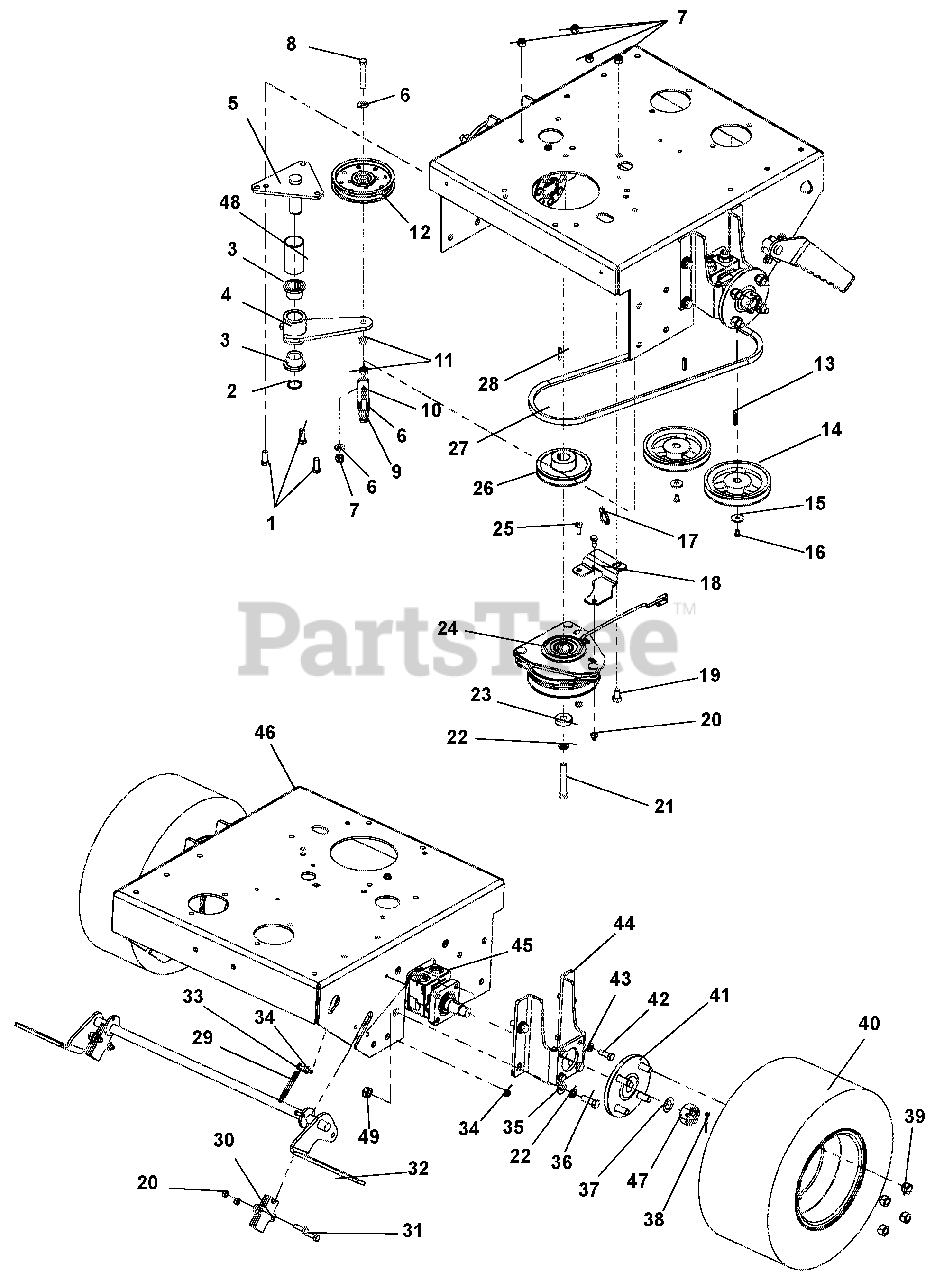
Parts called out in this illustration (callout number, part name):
1	BOLT-HEX .38-16 1.00 GR5
2	SNAP RING, 1.00 X .042 EXT
3	BRG, FLG 1.00 X 1.25 X 1.00
4	WLDT, IDLER ARM
5	WLDT, IDLER PIVOT MOUNT
6	WASHER, .406 X .813 X .065 FLAT Y
7	NUT-LOCKING-NYLON .38-16
8	BOLT, HEX .38-16X2.50 GRADE 5
9	BLT-HEX .38-16X3.00 HEX 8 YWZC
10	SPRING, EXT .900X.135X4.50 Y
11	NUT-SPIN LOCK-FLANGE .375-16
12	PULLEY, FLAT 4.50 X .375 W/BRG
13	KEY, M5 X M5 X M30 RD
14	ASSY, PUMP PULLEY W/SET SCREW
15	WASHER, .250 WIDE HEAVY FLAT Y
16	BOLT, M6 X 1.00 X 10 HEX 8.8 Y
17	CABLE TIE, .15 X 8.50
18	PLATE, CLUTCH DOG
19	BOLT, 7/16-14 X .750 HEX 5 Y
20	NUT-LOCKING-NYLON .312-18
21	BOLT, HEX .44-20 X 3.00 G5
22	WASHER-LOCKING .44X.109 REGULAR
23	SPACER, .468 X 1.38 X .375 Y
24	CLUTCH ASSY, OGURA
25	BOLT, HEX .31-18 X .75 GR5
26	PULLEY, V-BELT 4.45X1.00 W/KEY
27	BELT, HA 55.1 EL AMD OHR
28	KEY, .250 X .250 X .995 TPR
29	SPRING, EXT .375 X .055 X 2.25 Y
30	SHOE, BRAKE SYSTEM FLOAT WALK
31	BOLT, HEX .31-18 X 1.00 GR5
32	WLDT, BRAKE SYS FLOAT HYDRO (988324, 325)
32	WLDT, BRAKE SYS 36" FLWLK (988323)
33	BOLT, HEX .25-20 X 1.25 GR5 (SN 000101 - 020000)
34	LOCKNUT, 1/4-20 WHIZ Y (SN 000101 - 020000)
35	WASHER, .468 X 1.00X.125 FLAT Y
36	BOLT, HEX .44-14 X 1.25 GR5
37	BUSHING, MACH .750X1.25X.048 Y
38	PIN, COT .125 X 1.50 EXTP Y
39	NUT, 1/2-20 LUG C
40	ASSY, WHEEL & TIRE 16 X 7.5-8 (988324, 988325)
40	ASSM, WHEEL & TIRE 16 X 6.50-8 (988323)
41	ASSY, WHEEL HUB
42	BOLT, 3/8-16 X 1 GR8 BLACK
43	WASHER, .38 x .094 REG
44	BRKT, MOTOR MOUNT FLWLK (988323, 988324)
45	MOTOR, HYDRAULIC WHEEL
46	ASM, FRAME W/DECALS 36" GRAVELY (988323)
46	ASSM, 48-52" FRAME W/DECALS (988324, 988325)
47	NUT, .75 UNF2B HEX SLOT JDS14
48	BSHG, SPCR .505/.500 X .999/.996 X 2.05/2.03 PM
49	NUT-LK-NYL .44-14 YWZC
